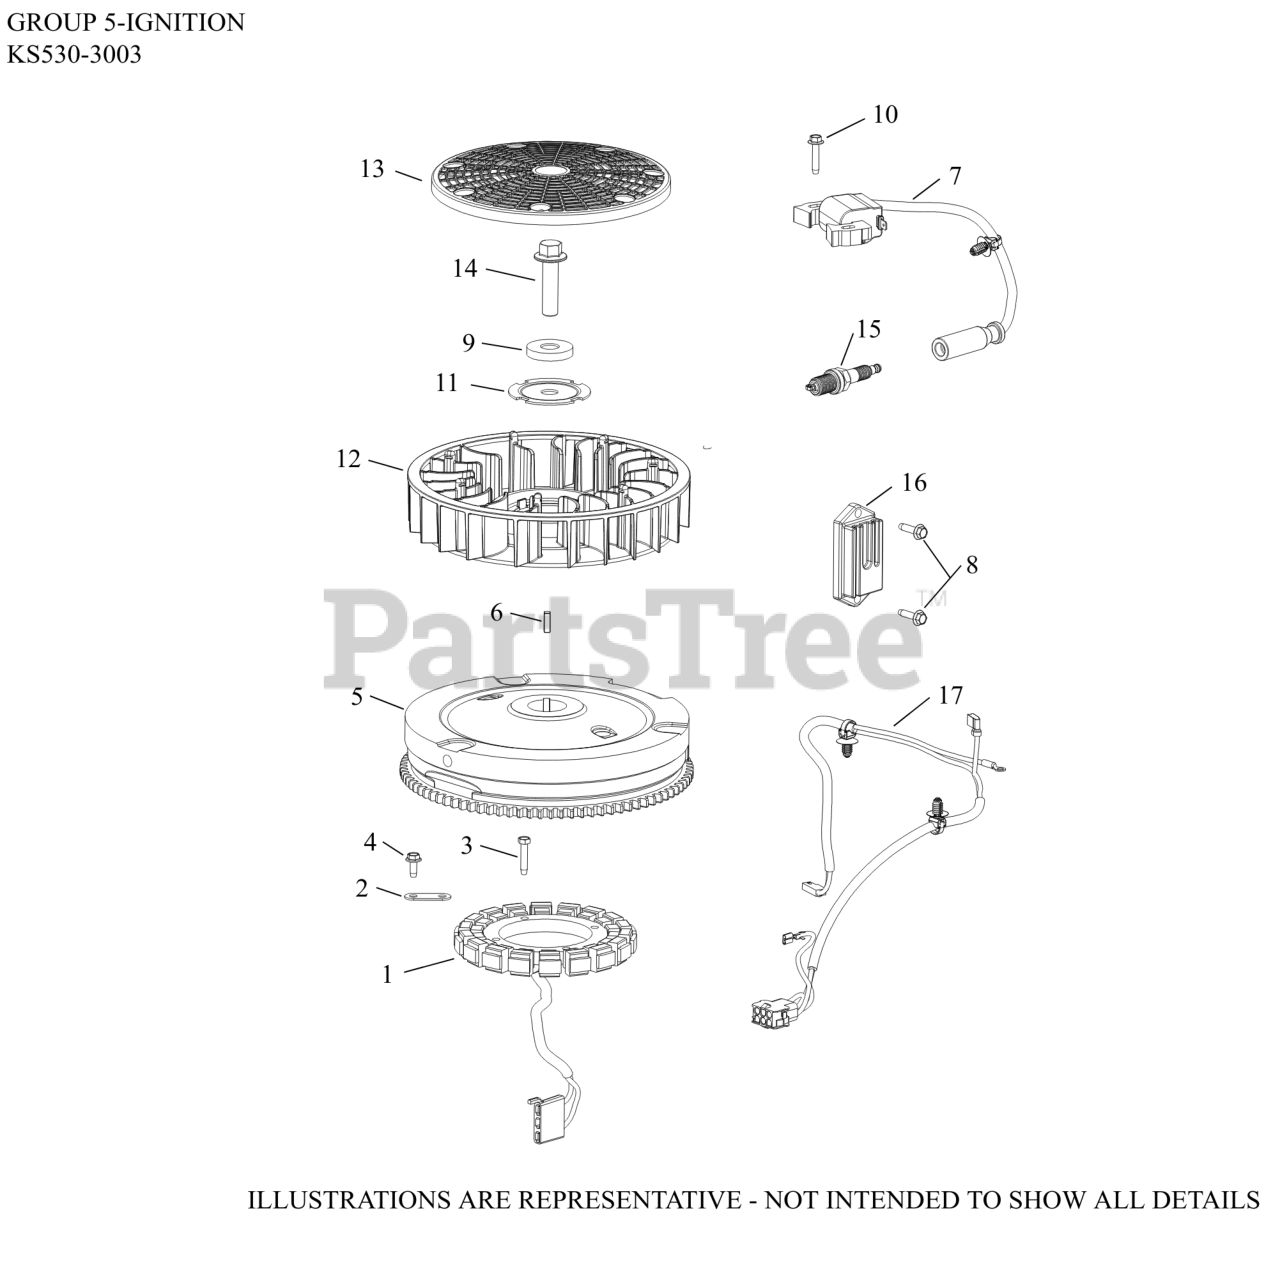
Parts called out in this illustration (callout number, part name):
1	STATOR ASSY, 12A
2	CLIP, STATOR WIRE
3	SCREW, THREAD FORMING
4	SCREW, FLG THD FRM M5X0.8X13
5	FLYWHEEL, ASSY
6	KEY, SQUARE
7	MODULE, INDUCTIVE IGNITION COIL
8	SCREW, THD FRM-USE 25 086 473-S
9	WASHER, FLAT
10	SCREW, THREAD FORMING
11	PLATE, FAN MOUNTING
13	SCREEN, GRASS
14	SCREW, HEX FLANGE
15	PLUG SPARK 12MM RFI
16	REGULATOR/RECTIFIER 12/15A HALF-WAVE STD
17	HARNESS, WIRING NON-OSU, NON MTD
